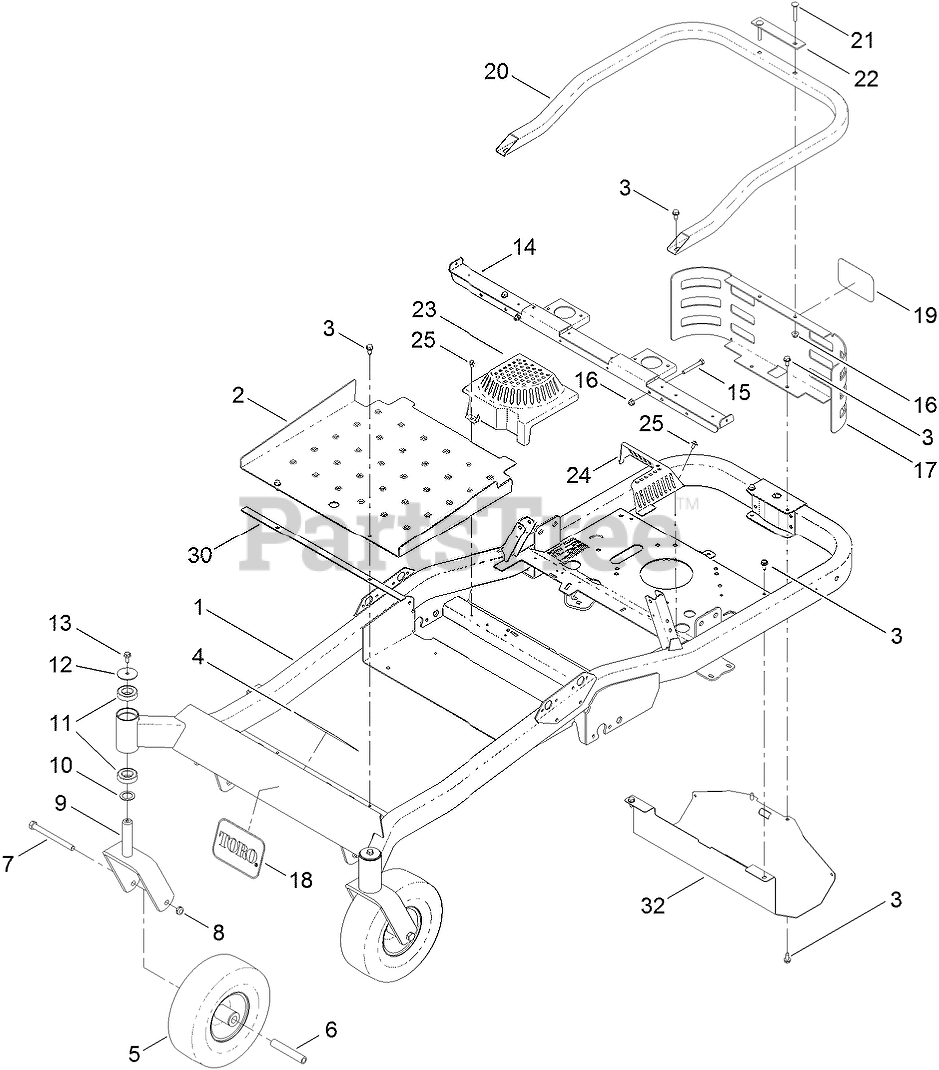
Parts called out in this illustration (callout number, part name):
2	PAN-FLOOR
3	SCREW-HWHTF
4	DECAL-SAFETY
5	WHEEL AND TIRE ASM
6	SPACER-SPANNER
7	SCREW-HH
8	NUT-LOCK, NI
9	FORK-CASTER
10	WASHER-THRUST
11	BEARING-BALL
12	WASHER
13	SCREW-HHF
14	SUPPORT-SEAT
15	SCREW-HH
16	NUT-HF, NI
17	GUARD-REAR
18	DECAL
20	GUARD-REAR, TUBE
21	Screw-CARR
22	PLATE-SPACER
23	COVER-FAN, RH
24	COVER-FAN, LH
25	SCREW-HHFTF
30	STRIP-VIBRATION, ANTI
32	GUARD-MUFFLER
